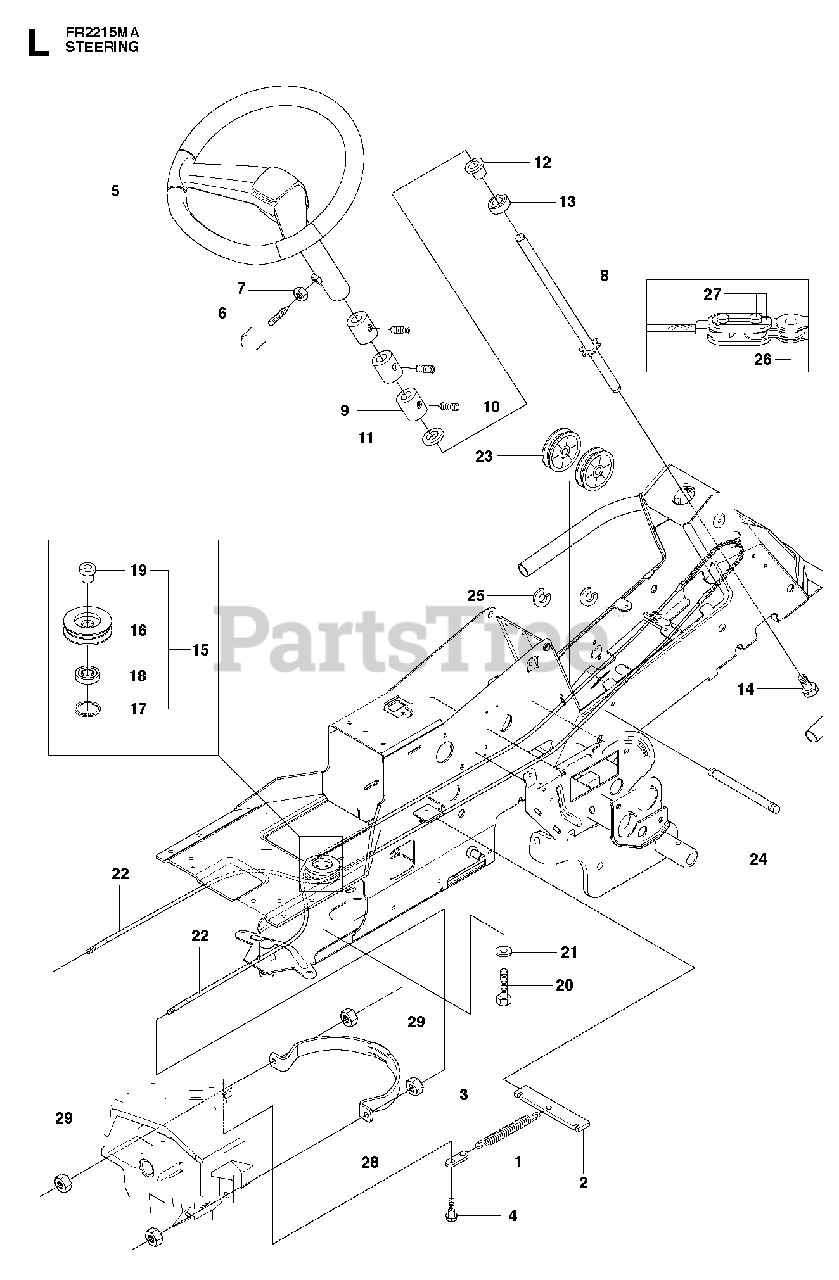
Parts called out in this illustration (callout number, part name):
2	SPRING BRACKET
3	CONNECTOR
5	STEERING WHEEL
7	NUT
8	ROD STEERING ASSY
9	SPACER
13	BALL BEARING 6004-2RS1
16	ROLLER
17	CIRCLIP SGH 47
18	BALL-BEARING 6204-2RS
19	BUSHING
20	COLLAR SCREW
22	RP STEERING CABLE COMPLETE
24	SHAFT
25	RETAINING RING
26	STEERING CHAIN
28	WIRE GUIDE
29	NUT
